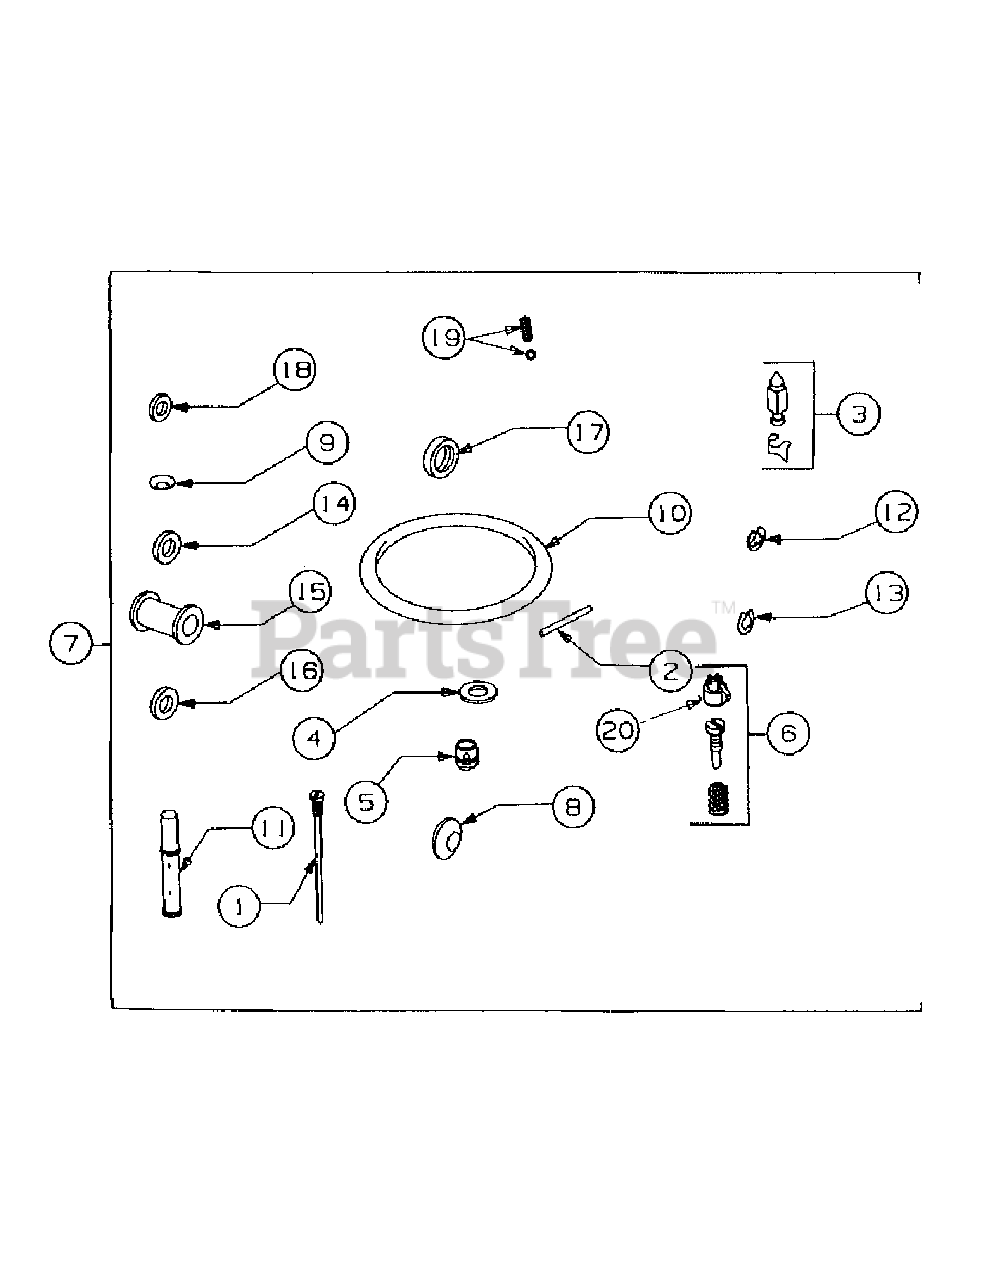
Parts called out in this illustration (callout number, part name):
1	Nozzle, Carburetor
2	Pin, Float Hinge
3	Valve, Fuel Inlet
4	Gasket, Sealing
5	Jet, Main
6	Valve Assembly, Carburetor Idle
7	Overhaul Kit, Carburetor
8	Plug, Welch
9	Plug, Welch
10	Gasket, Bowl Mtg
11	Nozzle
12	Retainer, Choke Shaft
13	Retainer, Throttle Shaft
14	Collar, Throttle
15	Collar, Throttle
16	Collar, Choke
17	Seal, Throttle Shaft
18	Seal, Choke Shaft
19	Ball, Choke Locator
20	Cap, Limiter
